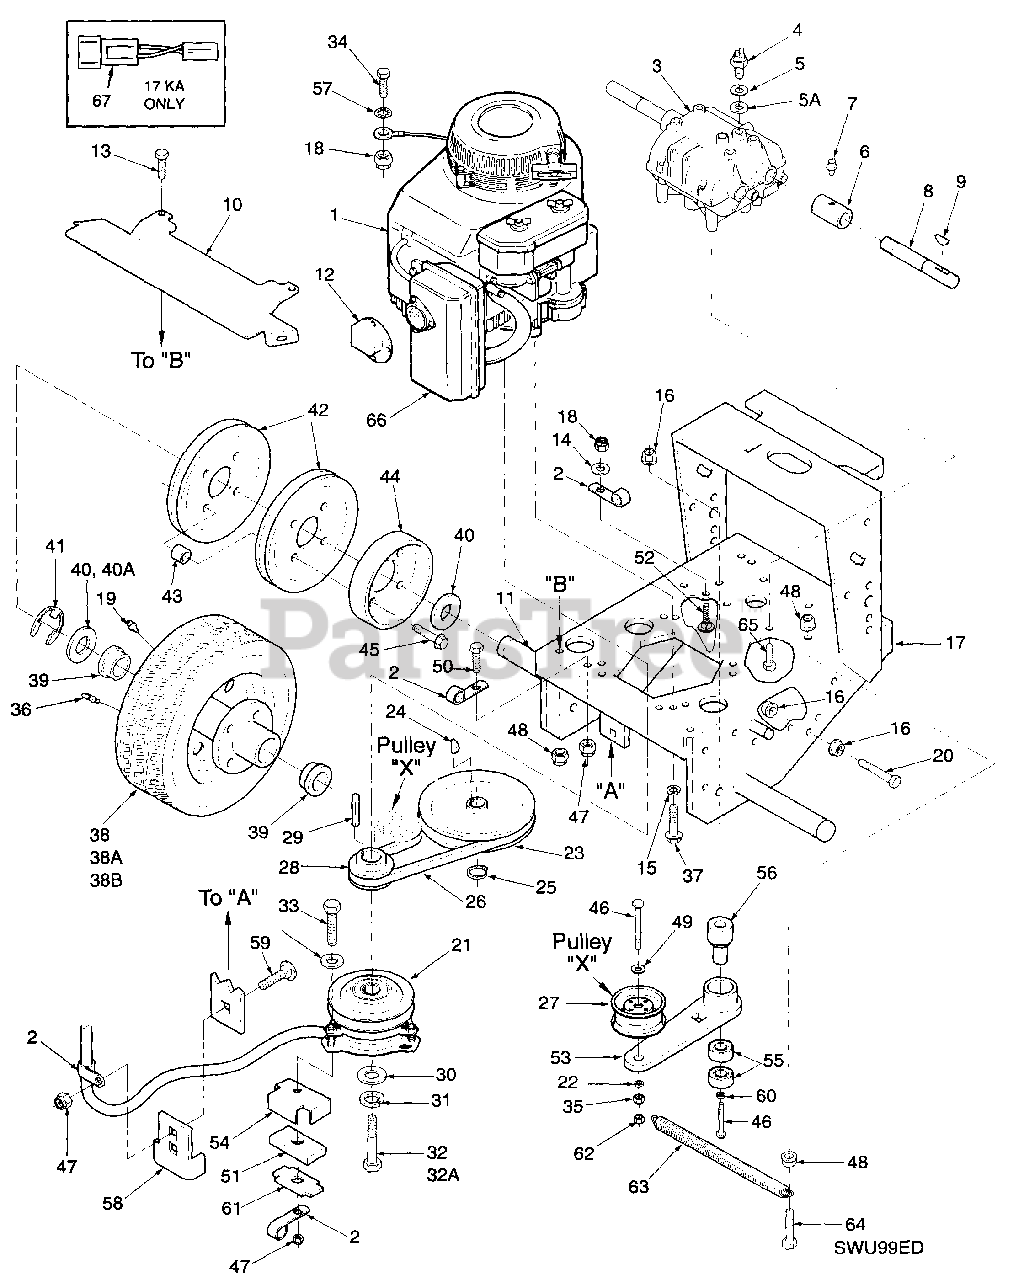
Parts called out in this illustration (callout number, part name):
1	Engine, 15HP Kohler
1	Engine, 17HP Kawasaki
2	Cable Clamp
3	Transmission, 5-speed
4	Neutral Safety Switch
5	Fibre Washer, thin
5A	Fibre Washer, thick
6	Coupler, Jackshaft
7	Grease Fitting, straight 1/4-28
8	Jackshaft
9	Key, Hi-Pro #9
10	Heat Shield
11	Wheel Axle
12	Exhaust Deflector
13	Bolt, 5/16-18 X 75" Serrated Flange Hex Head
14	Flat Washer 1/4" (.312 X .75 X .065)
15	Lock Wshr 5/16"
16	Nut, 3/8-16 Serrated Flange
17	Engine Deck
18	Nut, 1/4-20 Elastic Stop
19	Grease Fitting, 1/4-28 Self Tap
20	Bolt, 3/8-16 x 3-3/4" Hex Head
21	Electric Clutch (Ogura)
22	Washer, 3/8" (.391 x .938 x .105)
23	Pulley, Transmission Input
24	Key, Woodruff #9
25	Retaining Ring, 5/8" Ext, Basic
26	Belt, Transmission Drive
27	Idler Pulley, Transmission
28	Pulley, Traction Drive
29	Key, 1/4 x 1/4 x 3/4"
30	Flat Washer, 7/16" Special
31	Lock Washer, 7/16"
32	Bolt, 7/16-20 x 2-1/2" Hex Head
32A	Cpsrw, M10-1.5 x 55 Metric Hex Hd
33	Bolt, 5/16-18 x 1-3/4" Hex Head
34	Bolt, MS-1.25 x 1.0
35	Nut, 3/8-16 Elastic Stop
36	Valve Stem
37	Bolt, M8-1.25 x M25 Metric Hex Hd
38	Wheel Assembly
38A	Tire, 13 x 6.50-6, 2-ply
38B	Rim & Bearing Assembly
39	Wheel Brng NWC
40	Washer, 1-1/16 x 1-3/4 x 12 ga
40A	Washer, 1-1/16 x 1-1/2 x 18 ga
41	Retaining Ring, 1" Ext - "E"
42	Pulley, Wheel Drive
43	Spacer, Wheel Pulley
44	Brake Drum
45	Bolt, 5/16-18 x 1-1/2" Serrated Flange
46	Capscrew, Hex Head 3/8-16 x 2.75"
47	Nut, 5/16-18 Elastic Stop
48	Nut, 5/16-18 Serrated Flange Hex Head
49	Flatwasher, 3/8 (.391 x 938 x 105)
50	Bolt, 5/16-18 x 75" Hex Head
51	Rubber Pad, Clutch Stop
52	Bolt, 1/4-20 x 75" Carriage
53	Idler Arm, Trans Drive
54	Backing Plate
55	Ball Bearing
56	Hub Idler Pivot
57	Lock Washer Internal Tooth
58	Anti Rotation Bracket
59	Bolt, 5/16-18 x 1" Carriage
60	Flatwasher, 3/8 (.391 x .938 x .105 HD)
61	Plate, Backing
62	Nut, 3/8-16 Elastic Stop
63	Spring, Return Drive Idler
64	Bolt, Hex Head 3/8-16 x 2.75"
65	Capscrew, 5/16-18 x .75 Serrated Flange Hex Head
66	Muffler, Kohler
66	17KA Muffler
67	Wire Harness Adaptor, 17KA
